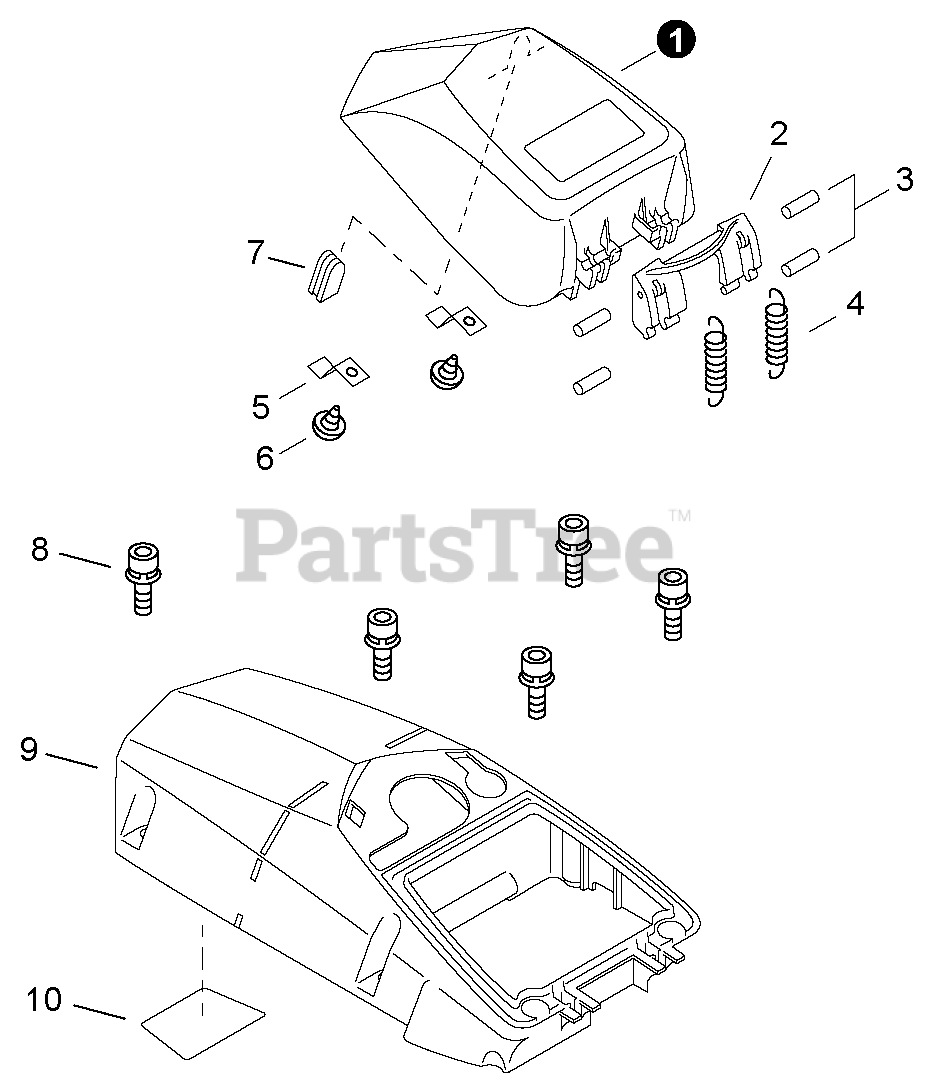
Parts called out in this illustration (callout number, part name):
1	COVER, AIR FILTER
2	LATCH, FILTER COVER
3	PIN 3×12
4	SPRING, TENSION
5	SPRING, FLAT
6	SCREW 4×10
8	BOLT 5×20
9	COVER, ENGINE
10	SHIELD, HEAT
